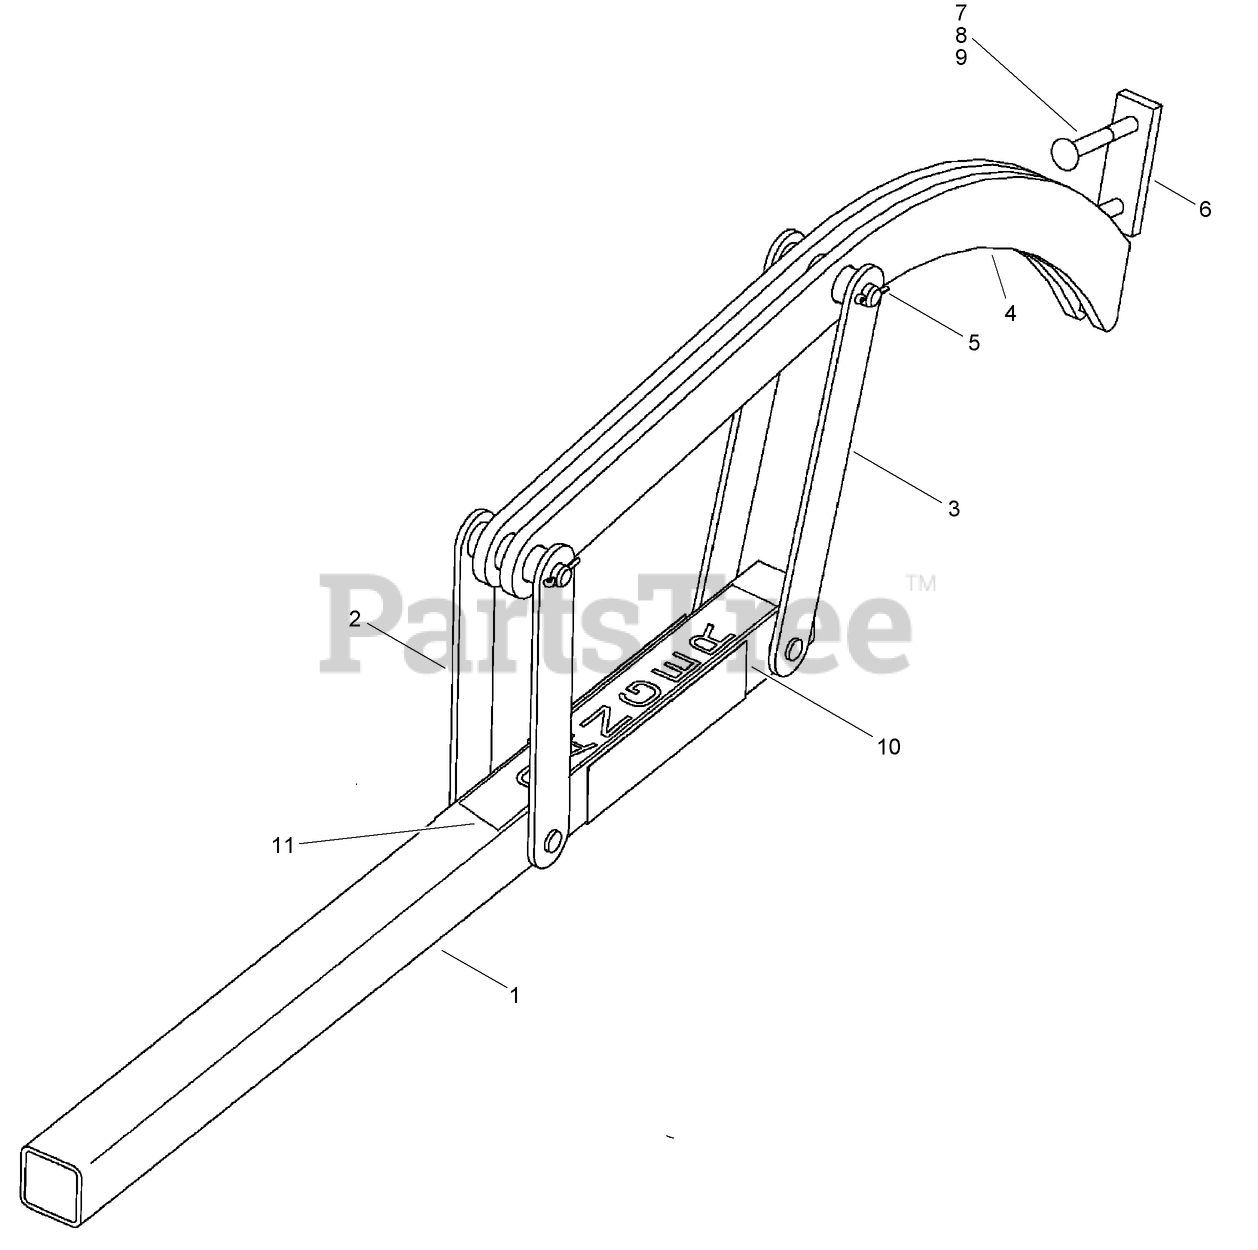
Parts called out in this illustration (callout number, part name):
1	TUBE-4 Foot Crumber
2	LINK-Crumber
3	LINK-boom to crumber, long
4	BLADE-Crumber
5	PIN-cotter, 3/16 x 1-1/4 inch
6	PLATE-spacer, bracket to blade
7	BOLT-CARR
8	WASHER-0.531 x 1.062 x 0.092 in CST ZND
9	NUT-LOCK, HEX
10	DECAL-Danger, Entanglement Hazard
11	DECAL-Danger
